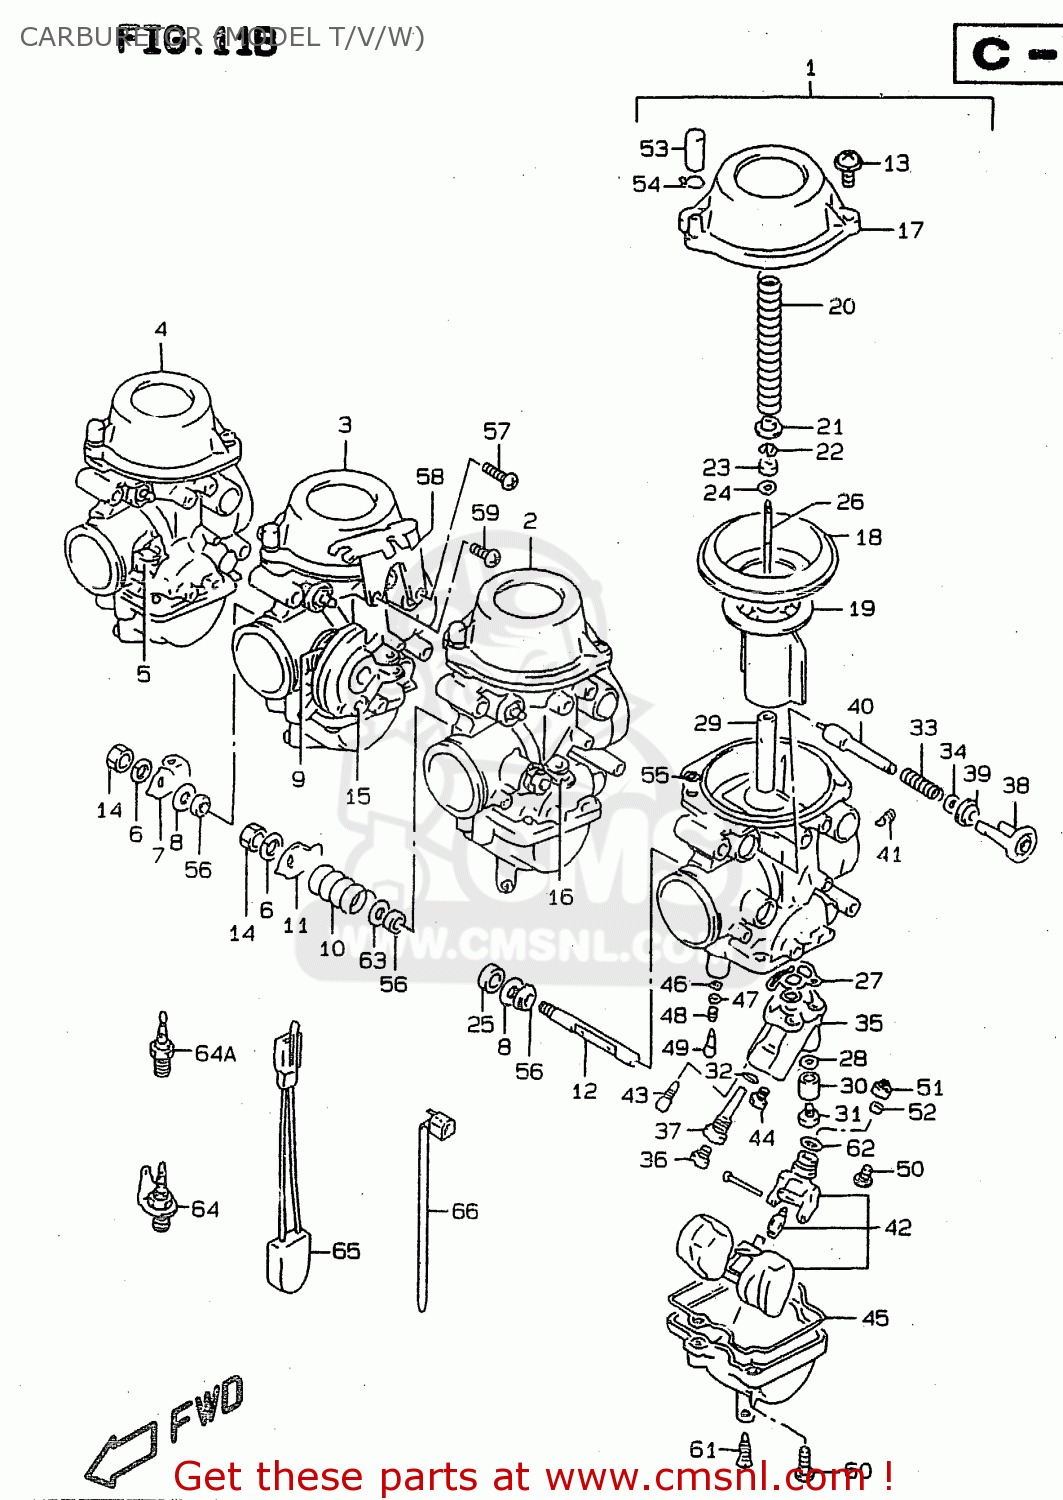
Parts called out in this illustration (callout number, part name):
1	CARBURETOR ASSY, LH
2	CARBURETOR ASSY, ML
3	CARBURETOR ASSY, MR
4	CARBURETOR ASSY, RH
5	SHAFT,THROTTLE
6	WASHER
7	LEVER,THROTTLE
8	GASKET,THROTTLE SHAFT (NAS)
9	SPRING
10	SPRING
11	SHAFT,THROTTLE
12	SHAFT,THROTTLE
13	SCREW
14	NUT
15	SHAFT,THROTTLE
16	LEVER,THROTTLE
17	COVER,DIAPHRAGM
18	DIAPHRAGM
19	VALVE,PISTON
20	SPRING
21	RING
22	E RING
23	RING
24	WASHER
25	RING
26	NEEDLE JET (5DV1)
27	O RING
28	GASKET (NAS)
29	JET,NEEDLE(O-9)
30	RING
31	SCREW
32	O RING
33	SPRING
34	WASHER
35	JET BLOCK ASSEMBLY
36	JET,MAIN(115)
37	HOLDER,JET
38	HOLDER,GUIDE
39	CAP,STARTER
40	PLUNGER ASSY
41	JET,PILOT AIR(120)
42	FLOAT/NEEDLE VALVE ASSY
43	JET,PILOT(12.5)
44	JET,STARTER(50)
45	SEAL
46	O RING,PILOT AIR SCREW
47	WASHER
48	SPRING
49	SCREW,PILOT
50	SCREW
51	FILTER
52	RING
53	CAP
54	CLIP
55	O RING
56	SEAL
57	SCREW(5X14)
58	BRACKET
59	SCREW
60	SCREW
61	SCREW,DRAIN
62	O-RING,NEEDLE VALVE
63	RING
64	HEATER ASSY,CARBURETOR(15W)
64A	HEATER, CARB.
65	THERMO SWITCH,CARB HEATER
66	CLAMP(L:125)
